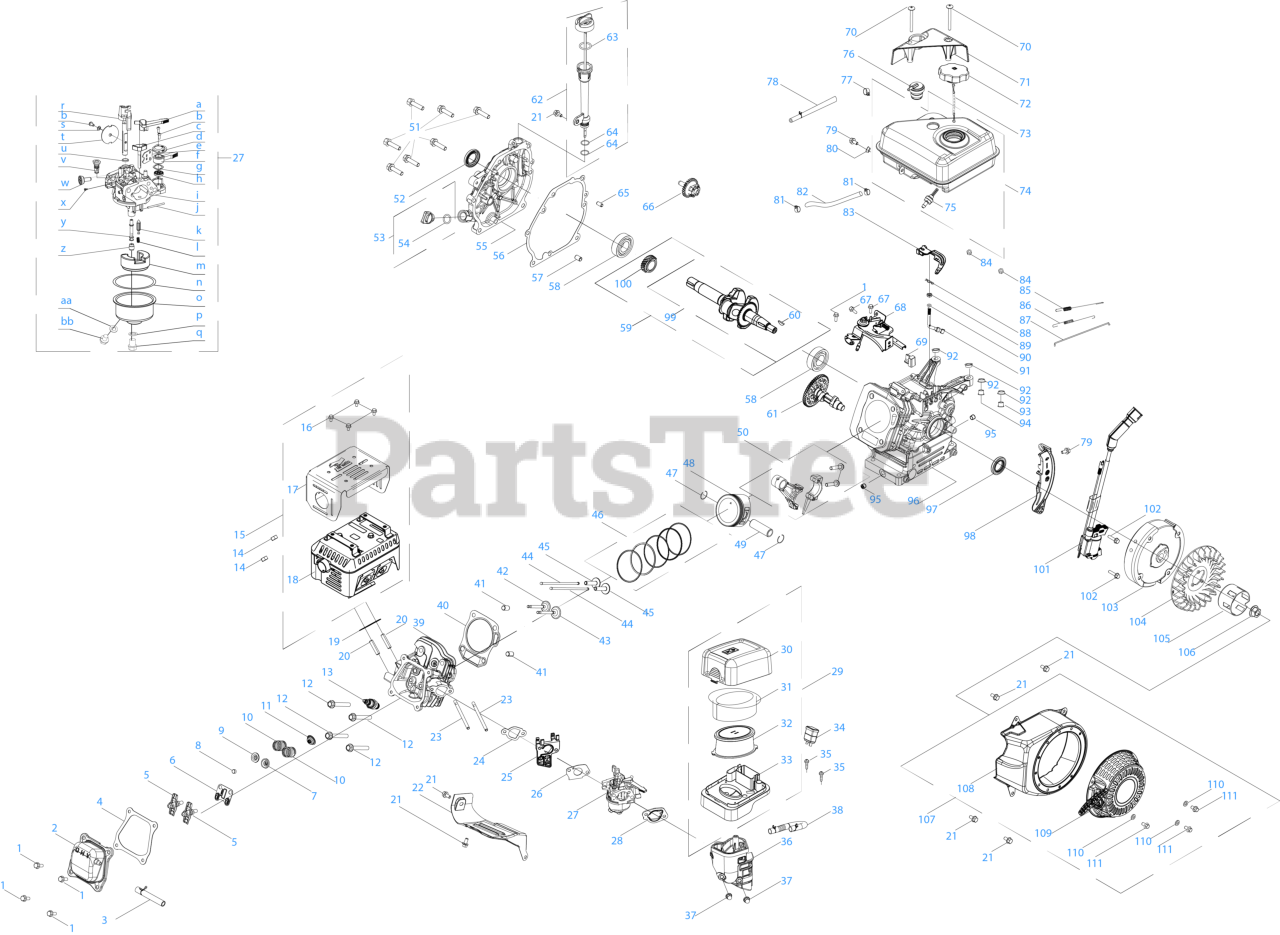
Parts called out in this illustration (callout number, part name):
1	BOLT M6 x 16
2	VALVE COVER
3	BREATHER HOSE
4	VALVE COVER GASKET
5	ROCKER ARM ASSEMBLY
6	ROCKER ARM BASE
7	INTAKE VALVE SPRING RETAINER
8	EXHAUST VALVE ADJUSTER
9	EXHAUST VALVE SPRING RETAINER
10	VALVE SPRING
11	INTAKE VALVE SEAL
12	BOLT-M8-1.25 x 60 GR10.9
13	SPARK PLUG
15	MUFFLER ASSEMBLY
16	BOLT M5-.8 x 8 CL10.9
17	MUFFLER GUARD
18	MUFFLER BODY
19	MUFFLER GASKET
20	STUD M8 x 36
21	BOLT M6-1 x 12 GR8.8
22	AIR SHIELD
23	STUD M6-1 x 110 GR8.8
24	CARBURETOR INSULATOR GASKET
25	CARBURETOR INSULATOR
26	CARBURETOR GASKET
27	CARBURETOR
28	CARBURETOR GASKET PLATE
29	AIR FILTER
30	AIR FILTER COVER
31	AIR FILTER
32	AIR CLEANER WITH PRE-FILTER
32	Genuine Factory Parts AIR FILTER
33	SILENCER PLATE
34	CARBON CANISTER
35	SCREW M4x20
36	AIR CLEANER HOUSING
38	PRIMER HOSE
39	CYLINDER HEAD
40	CYLINDER HEAD GASKET
42	EXHAUST VALVE
43	INTAKE VALVE
44	PUSH ROD
46	PISTON RING 4PC SET
47	PISTON PIN SNAP RING
49	PISTON PIN
50	CONNECTING ROD ASSEMBLY
51	BOLT M8-1.25 x 32 GR5.8
52	OIL SEAL 25 x 41.25 x 6
54	O-RING 15.8 x 2.5
55	CRANKCASE COVER
56	CRANKCASE GASKET
57	DOWEL PIN
59	CRANKSHAFT
60	FLYWHEEL KEY
62	DIPSTICK ASSEMBLY
63	DIPSTICK O-RING
64	OIL FILL TUBE O-RING
65	DOWEL PIN
66	GOVERNOR GEAR/SHAFT ASSEMBLY
67	BOLT M6-1 x 12 GR8.8
68	GOVENOR GEAR BRACKET
69	THROTTLE KNOB
70	BOLT M6-1 x 67
71	ENGINE/DIPSTICK COVER
72	FUEL CAP BLACK
75	FUEL INLET NIPPLE
76	ROLLOVER VALVE
77	FUEL HOSE CLAMP
78	HOSE ASSEMBLY
79	SCREW M6-1 x 20 CL5.8
80	GROMMET-8.5 x 9
81	HOSE CLAMP
82	FUEL HOSE, 6.3x12.5x115
83	GOVERNOR LEVER
85	GOVERNOR SPRING
86	THROTTLE RETURN SPRING
87	GOVERNOR ROD
88	COTTER PIN
89	GOVERNOR SEAL
91	GOVERNOR SHAFT
92	RUBBER SEAT
93	GROMMET-8.5 x 24.5
94	GROMMET-8.5 x 17
95	OIL DRAIN PLUG
96	CRANKCASE
97	OIL SEAL-25 x 41.25 x 6
98	LOWER SHIELD
99	CRANKSHAFT
100	DRIVE TIMING GEAR
101	IGNITION MODULE
102	BOLT M6-1 x 25 GR8.8
104	COOLING FAN
105	STARTER CUP
106	FLYWHEEL NUT
107	RECOIL STARTER
108	BLOWER HOUSING
109	RECOIL STARTER
110	RECOIL FLAT WASHER
111	BOLT M6 x 10
